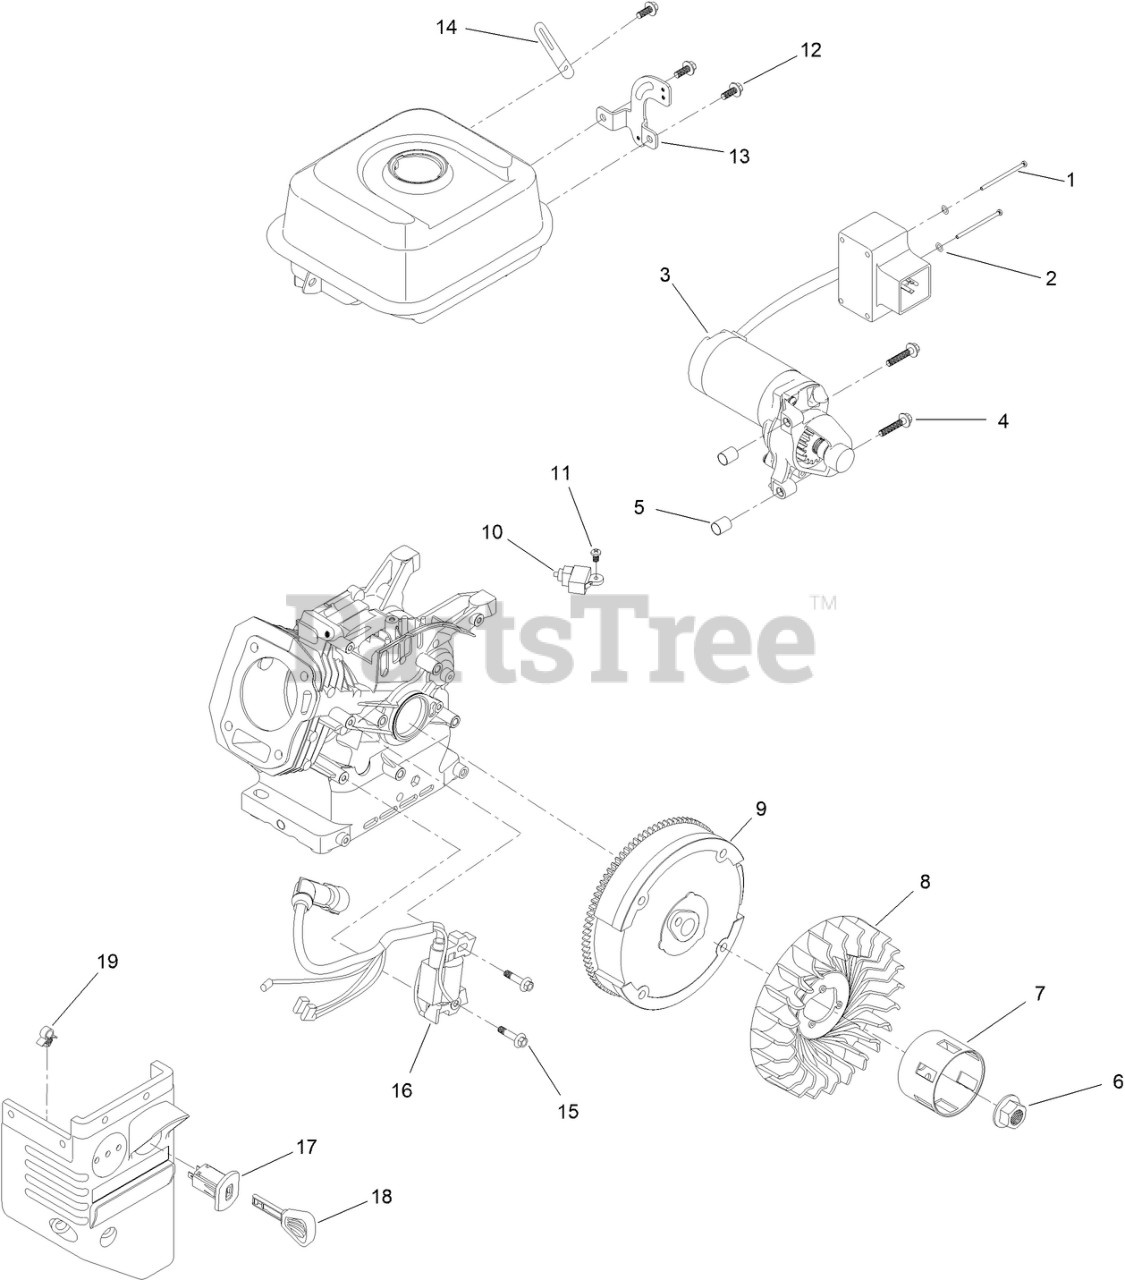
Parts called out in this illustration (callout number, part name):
1	SCREW-BHP
2	WASHER-PLAIN
3	MOTOR-STARTER
4	SCREW-FLANGE
5	PIN-DOWEL
6	NUT-FLANGE
7	CUP-STARTER
9	FLYWHEEL
10	SWITCH-KILL, ENGINE
11	SCREW-PPH
12	SCREW-HHF
13	BRACKET
14	CLIP-HARNESS, WIRE
15	SCREW-HHF
16	IGNITION COIL ASM
17	SWITCH-KEY
